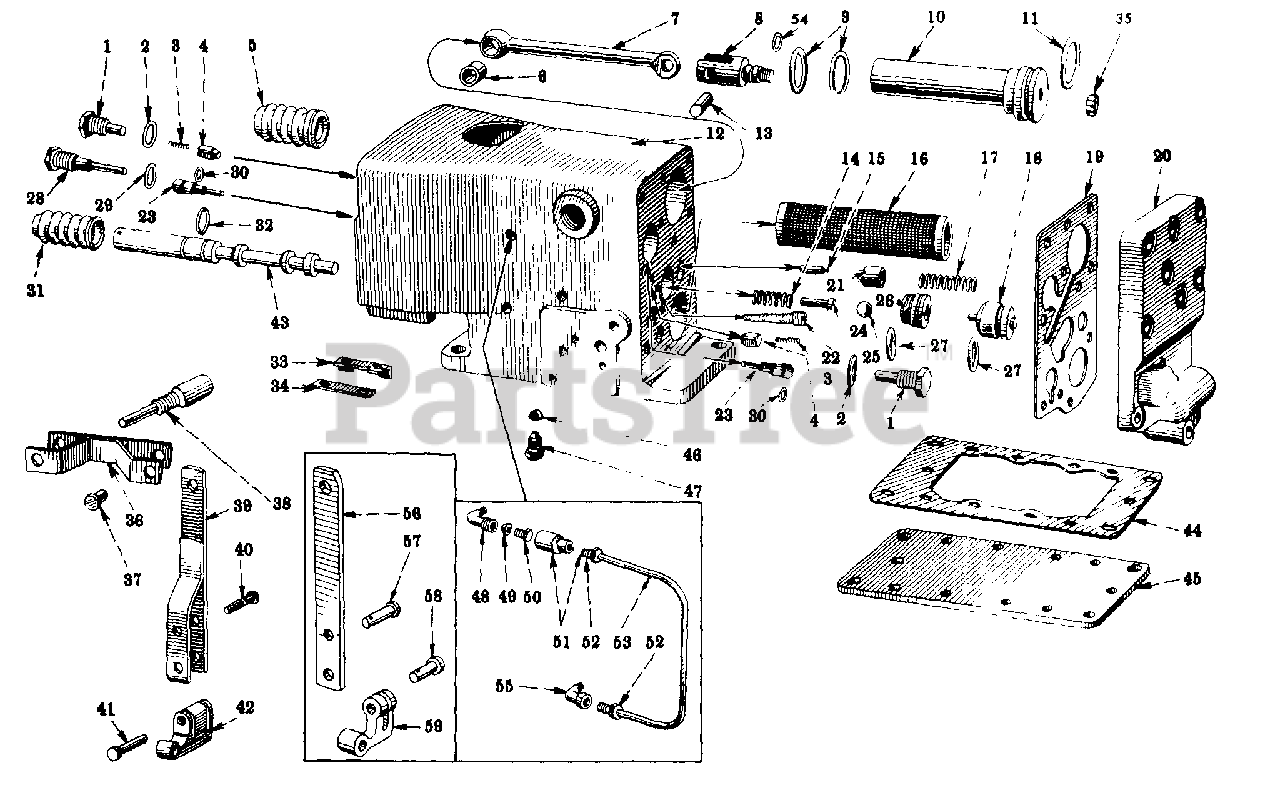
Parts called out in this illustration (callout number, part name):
1	PLUG, CHECK VALVE ACTUATOR
2	WASHER, CHECK VALVE ACTUATOR PLUG
3	SPRING. CHECK VALVE
4	VALVE, CHECK
5	BOOT, PISTON SLEEVE -RUBBER-
6	BUSHING. CONNECTING ROD
7	ROD W/BUSHING, IH-352007-R1, CONNECTING
8	YOKE, CONNECTING ROD
9	RING, PISTON SLEEVE SEAL
10	PACKAGE, PISTON REPLACEMENT SERVICE
10	PISTON ASSY
11	RING, PISTON HEAD SEAL
12	BLOCK ASSY. CYLINDER
13	PIN, CONNECTING ROD YOKE
14	SPRING, PRESSURE REGULATOR VALVE BALL RIDER
15	PISTON, SAFETY VALVE
16	STRAINER ASSY, CYLINDER BLOCK OIL
17	SPRING, SAFETY VALVE
18	PISTON ASSY, PRESSURE REGULATOR VALVE
19	GASKET, CYLINDER HEAD
20	HEAD ASSY, CYLINDER
20	HEAD W/PLUGS
21	SLEEVE, SAFETY VALVE
22	ORIFICE ASSY
23	ACTUATOR, CHECK VALVE
24	RIDER, PRESSURE REGULATOR VALVE BALL
25	BALL, 9/16 DIAMETER CHROME STEEL
26	SEAT, PRESSURE REGULATOR VALVE
27	RING. PRESSURE REGULATOR VALVE PISTON SEAL
28	STOP, CHECK VALVE ACTUATOR LOWER
29	WASHER, CHECK VALVE ACTUATOR STOP
30	O-RING, 3/8 X 1/2 X 1/16
31	BOOT, CONTROL VALVE -RUBBER-
32	RING, CONTROL VALVE SEAL
33	STOP, CONTROL VALVE OPERATING LEVER
34	LOCK, CONTROL VALVE OPERATING LEVER STOP
35	NUT, 1/2-20 PHC GRIPCO LOCK TYPE 8 CONNECTING ROD YOKE
36	LINK ASSY, CONTROL VALVE OPERATING
37	PIN, CONTROL VALVE OPERATING LINK
38	PIN, CONNECTING ROD
39	LEVER ASSY, CONTROL VALVE OPERATING
40	PIN, CONTROL VALVE -1-3/8 IN. LONG-
41	PIN, CONTROL VALVE OPERATING LEVER
42	YOKE, CONTROL ROD ADJUSTABLE -2 IN. LONG-
43	VALVE, CONTROL
44	GASKET, CYLINDER BLOCK COVER
45	COVER, CYLINDER BLOCK BOTTOM
46	SCREEN, RELIEF VALVE
47	VALVE ASSY, RELIEF
48	ELBOW W/SCREEN, IH-354269-R1 AND VALVE, IH-354264-R91, RELIEF VALVE
49	SCREW, RELIEF VALVE
50	VALVE ASSY, RELIEF
51	COUPLING W/NUT, IH-19984-R1, RELIEF VALVE
52	NUT, 7/16-24 NYLON INSERT HI-DUTY TUBE FITTING
53	TUBE W/TWO NUTS, IH-19984-R1, RELIEF VALVE
54	O-RING, 7/16 X 5/8 X 3/32
55	ELBOW, 7/16-24 X 90 DEG HI-DUTY TUBE MALE PIPE
56	LEVER, CONTROL VALVE OPERATING
57	PIN, CONTROL VALVE - 1-1/8 IN. LONG
58	PIN, CONTROL VALVE OPERATING LEVER
59	YOKE, CONTROL ROD ADJUSTABLE -1 IN LONG-
